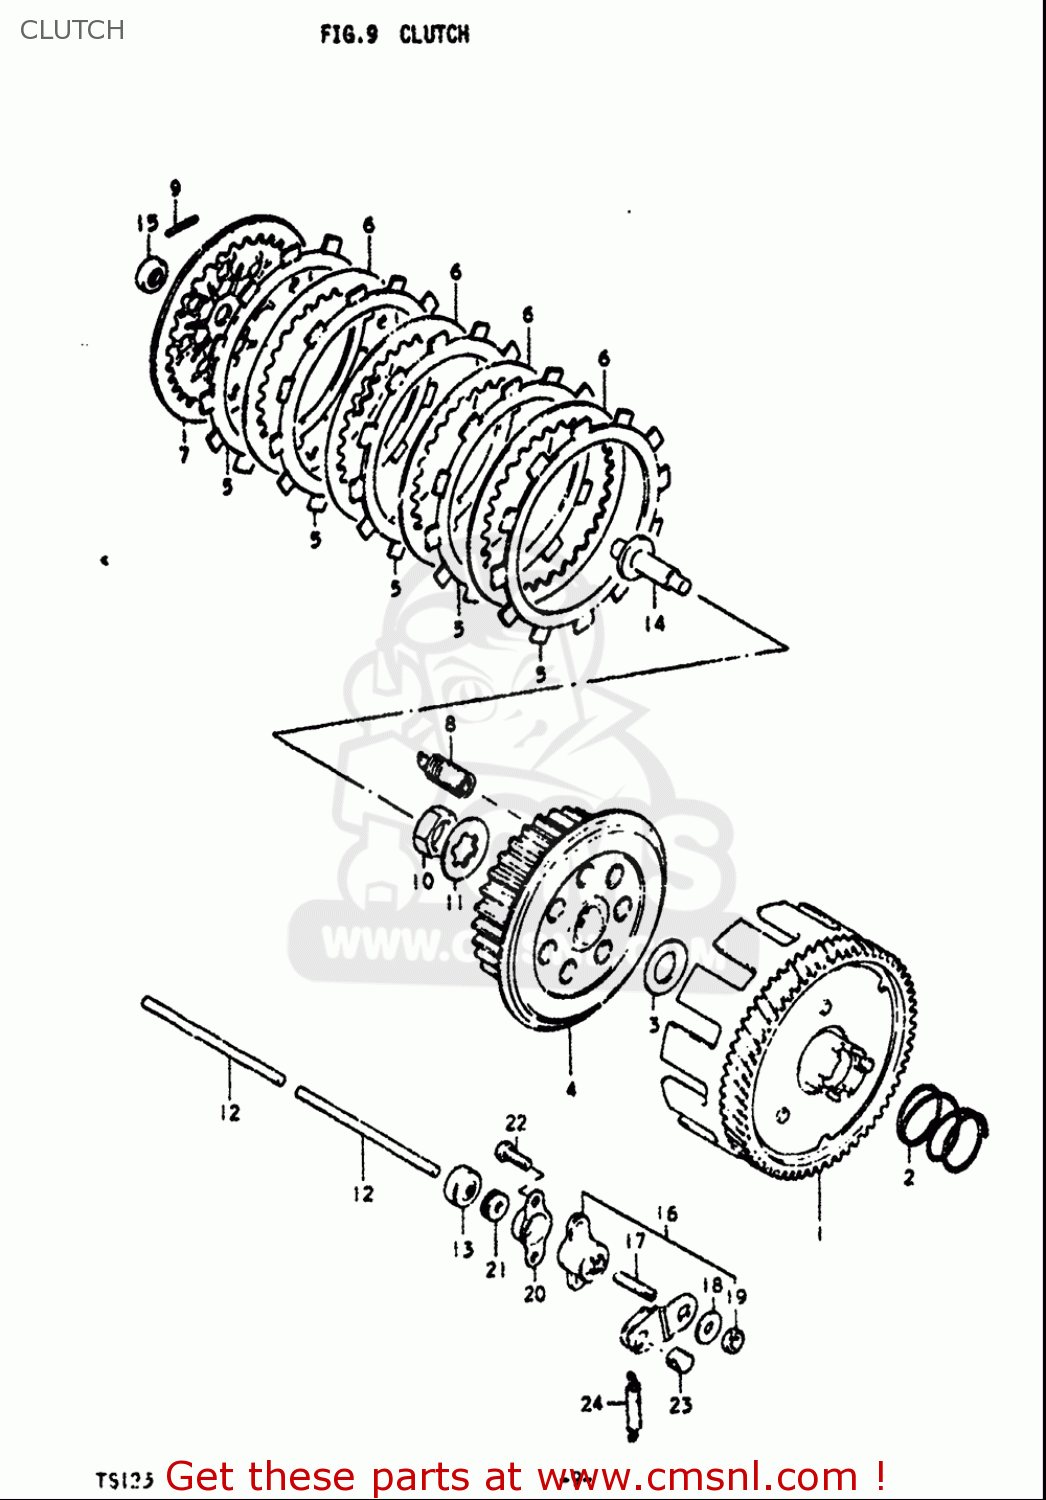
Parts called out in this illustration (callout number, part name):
2	SPRING
3	WASHER
4	HUB,CLUTCH SLEEVE
5	PLATE,CLUTCH DRIVE(T:3.0) (NAS)
6	PLATE,CLUTCH DRIVEN (NAS)
7	PLATE,CLUTCH PRESSURE
8	SPRING
9	PIN(2.5X19.8)
10	NUT
11	WASHER,LOCK
12	ROD,CLUTCH PUSH,L
13	SEAL,OIL(6X19X7)
14	ROD,CLUTCH RELEASE
15	SEAL,OIL (10X17X5)
16	SCREW ASSY,CLUTCH RELEASE
17	SCREW(6X25)
18	WASHER(6.5X16X1.2)
19	NUT
20	COVER,CLUTCH RELEASE SCREW
21	SEAL,DUST(5.3X13X5)
22	SCREW
23	PIECE,RELEASE ARM END
24	SPRING
